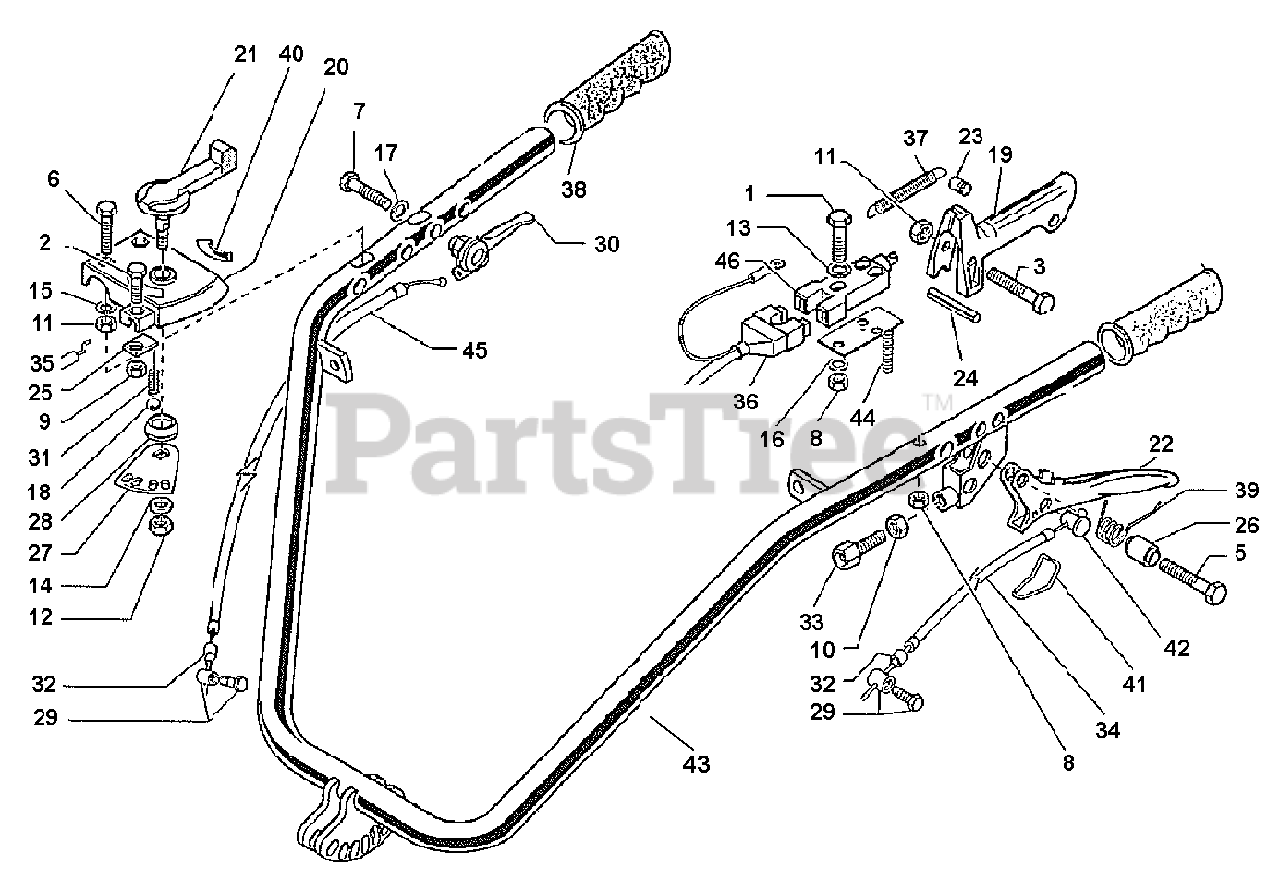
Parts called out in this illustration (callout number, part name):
1	SCREW TE M4 X 25
2	SCREW M5 X 10
4	SCREW TE M6 X 45
5	SCREW M6 X 25
6	SCREW M6 X 40
7	SCREW TE M8 X 40
11	NUT, SELF LOCKING M6
12	NUT, SELF LOCKING M8
13	FLAT WASHER 4.3
14	FLAT WASHER 13
15	LOCK WASHER 6.4
16	LOCK WASHER 4.3
17	LOCK WASHER 8.4
19	MOTOR STOP LEVER
21	THROTTLE LEVER
24	LEVER STOP FOR MOTOR STOP
26	LEVER SPACER
27	THROTTLE LEVER
29	CLAMP, CABLE
30	LEVER, ACCELERATOR
33	SCREW, ADJUSTING M8
34	CLUTCH CABLE, COMPLETE
35	THROTTLE CABLE, B&S
37	MOTOR STOP SPRING
39	LEVER SPRING
40	GAS DECAL FOR ENGINE
44	STOP SWITCH SUPPORT
45	THROTTLE CABLE ACME A220
45	THROTTLE CABLE ACME ALN330
45	THROTTLE CABLE KOHLER 8HP
46	STOP SWITCH
